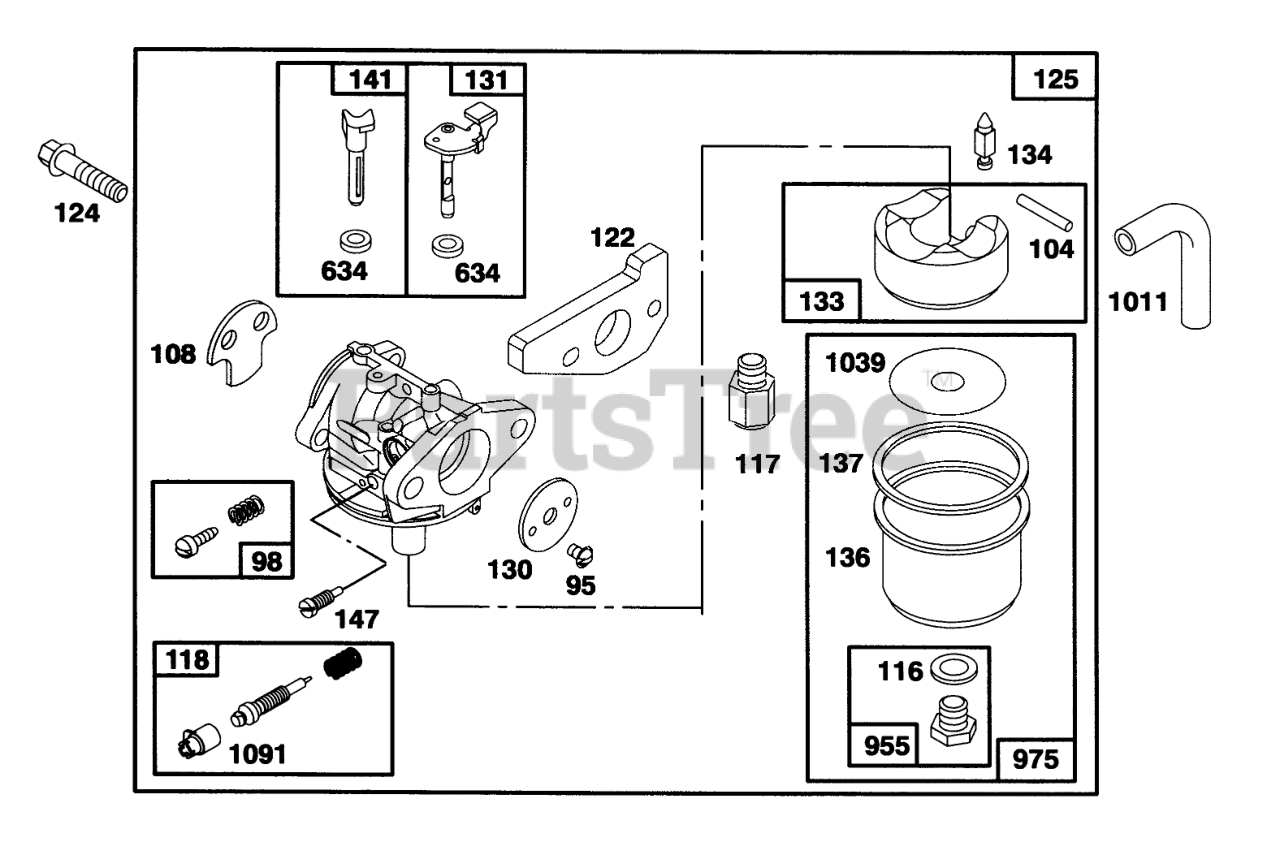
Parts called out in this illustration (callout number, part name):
95	Screw-Valve Mtg.
98	IDLE ADJUSTING SCREW
104	FLOAT HINGE PIN
108	VALVE - CHOKE
116	SEALING GASKET
117	JET - MAIN
118	VALVE/SPRING - NEEDLE
122	ADAPTER ASSEMBLY
124	HEX HEAD SCREW
125	ASSEMBLY - CARBURETOR
130	THROTTLE VALVE
131	THROTTLE SHAFT
133	FLOAT-CARBURETOR
134	Valve-lnlet (Includes Seat)
136	FLOAT BOWL
137	FLOAT BOWL GASKET
141	CHOKE SHAFT
147	JET - PILOT
634	SEAL WASHER
955	HEX HEAD SCREW
975	CARBURETOR BOWL ASM
1011	VENT TUBE
1039	FLOAT LIMITER
1091	CAP - LIMITER
